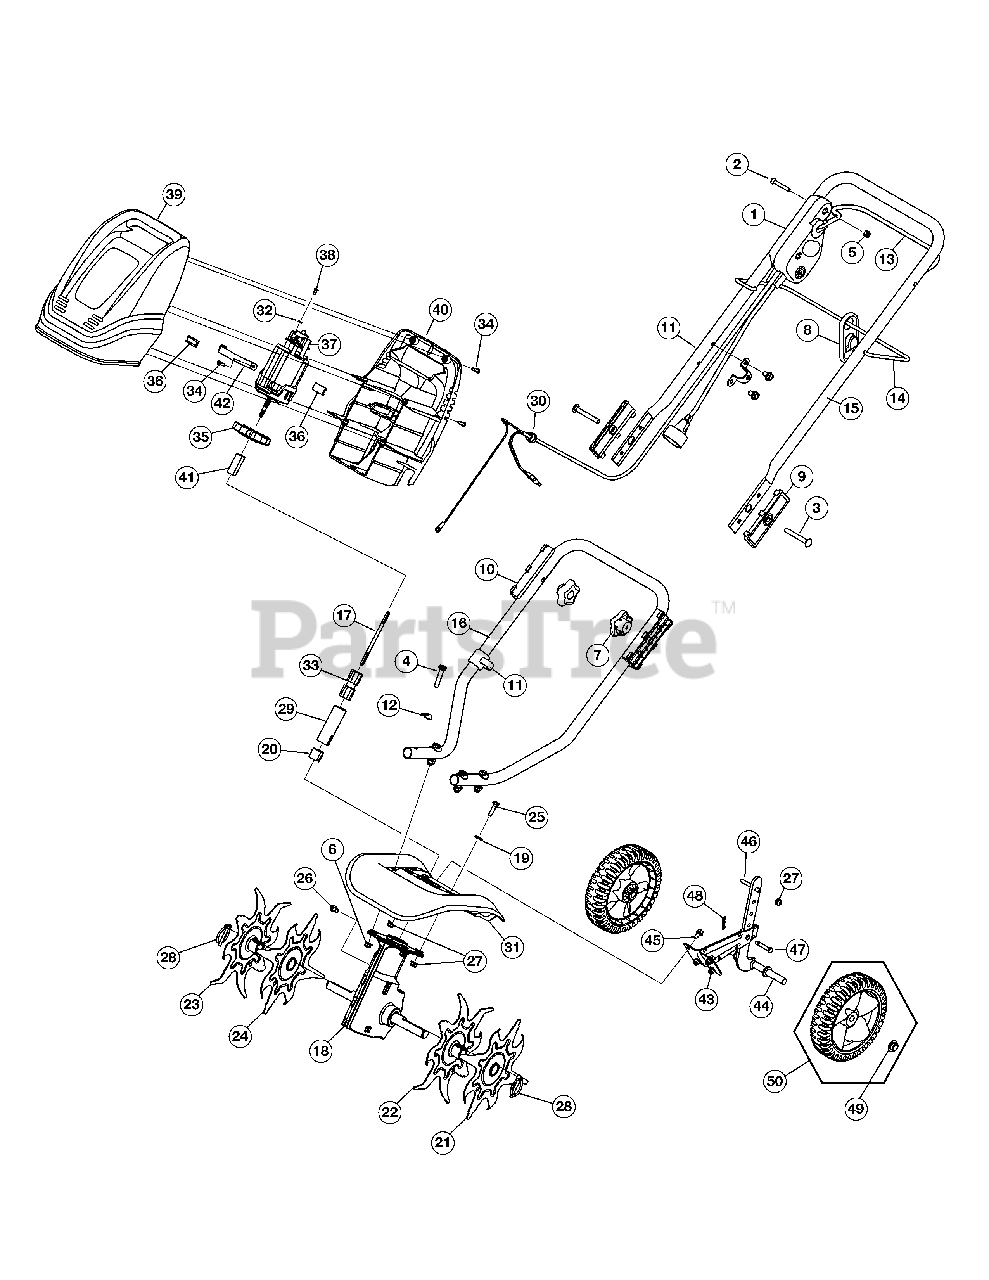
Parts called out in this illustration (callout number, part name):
1	Switch Assembly
4	Screw
8	Cord Retainer
9	Upper Handle Insulator
10	Lower Handle Insulator
11	Cable Guide
12	Saddle Washer
13	Control Bail
15	Upper Handle
16	Lower Handle
17	Flex Shaft
18	Gearbox
19	Washer
20	Sleeve
21	Outer Tine Assembly
22	Inner Tine Assembly
23	Outer Tine Assembly
24	Inner Tine Assembly
25	Screw
26	Bolt
28	Lynch Pin
29	Boom Tube
30	Cord Bushing
31	Tine Shield
32	Lock Washer
33	Flex Tube Assembly
36	Motor Pad
37	Motor Assembly
39	Front Motor Cover
40	Rear Motor Cover
41	Motor Hub
42	Motor Strap
43	Bracket Assembly
44	Wheel Support Bracket Assembly
46	Belt Guard Pin
47	Clevis Pin
48	Cotter Pin
49	Push Cap
50	Wheel (includes 49)
